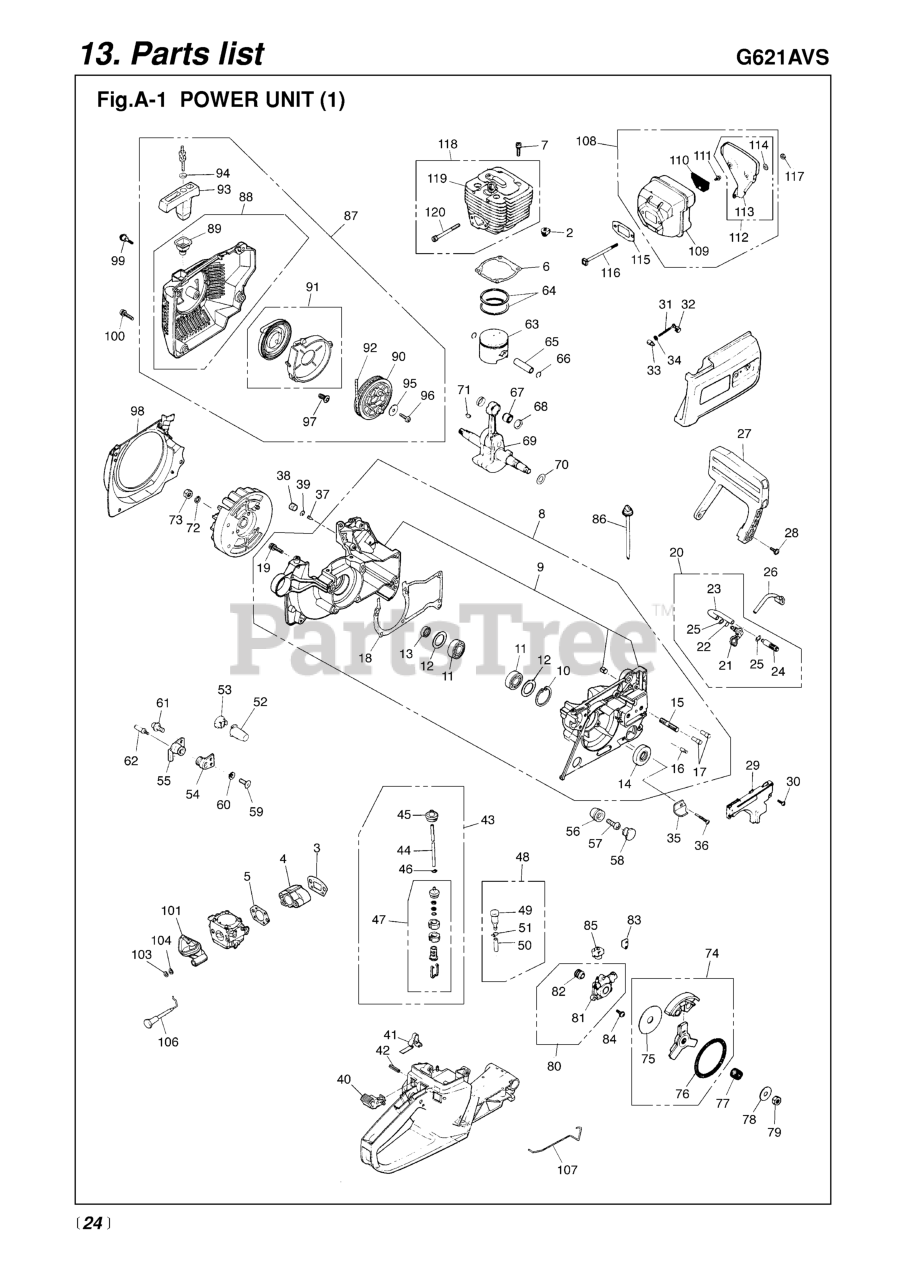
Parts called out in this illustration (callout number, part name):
2	GROMMET
3	GASKET, INS. (RPLS 2616-14112)
4	INSULATOR
5	GASKET, CARB (RPLS 2618-14131)
6	GASKET, CYLINDER (RPLS.-14210)
7	BOLT M5 x 20 (RPLS -12280)
8	CRANKCASE-ASSY
9	CRANKCASE (RPLS 2616-21101)
10	RING, SNAP, M35 X 1.5
11	BEARING (REPLACES 2810-21240)
12	RING
13	SEAL, OIL
14	SEAL (REPLACES 1400-21220)
15	STUD (RPLS 0205-50825)
16	PIN
17	PIN
18	GASKET (REPLACES 3356-21311)
19	BOLT M5 x 20 (RPLS -12280)
20	OIL PIPE COMP
21	PIPE, OIL
24	WEIGHT
26	PIPE, OIL
28	SCREW (REPLACES 2616-24320)
29	COVER, BRAKE (RPLS -24411)
30	SCREW, M5 x 14
31	ADJUST SCREW
32	STOPPER, ADJUS
33	NUT (A)
34	WASHER, M5 X .8
35	CATCHER, CHAIN (RPLS -25210)
37	VALVE (RPLS -23120)
38	SEAL, BREATHER
39	CLIP
40	SWITCH LEVER
41	SPRING
42	PIN, SPRING
43	PIPE ASSEMBLY
44	PIPE, SUCTION
45	GROMMET
46	CLIP (REPLACES 2841-31280)
47	FILTER ASSY
48	BREATHER ASSEMBLY
49	BREATHER ASSY (RPLS 2630-31270
51	CLIP (REPLACES 2841-31280)
52	DAMPER (RPLS -35111)
53	CAP (RPLS -35120)
54	DAMPER (RPLS -35150)
55	DAMPER (REPLACES -35131)
56	DAMPER (RPLS 2670-35110)
57	SCREW
58	CAP
59	SCREW, M5 X 14
61	SCREW
63	PISTON
64	RING
65	PIN, PISTON
66	RING, SNAP
67	BEARING
68	WASHER (RPLS 1491-41510)
69	CRANKSHAFT (RPLS -42003)
70	SHIM (REPLACES 848-870-G000)
71	KEY
72	WASHER, M10 X 25
73	NUT
74	CLUTCH ASSY (RPLS -51200)
75	PLATE
76	SPRING (RPLS -51230)
77	BEARING
78	WASHER
79	NUT
80	OIL PUMP (RPLS 3356-55102)
81	BODY, OIL PUMP
82	GEAR, WORM
83	GASKET, PUMP
84	SCREW, M5X20 (RPLS.1400-75510)
85	GROMMET (RPLS -55451)
86	SHAFT
87	STARTER ASSY (RPLS. -75003)
88	CASE (RPLS -75101)
89	GUIDE
90	REEL
91	SPRING COMP (RPLS. -75301)
92	ROPE
93	KNOB, STARTER
96	SCREW
98	COVER
99	SCREW (REPLACES 2616-75710)
100	SCREW
101	MANIFOLD (RPLS -82112)
103	WASHER, SPRING M4 x 1.3
104	WASHER, M5 X .8
106	ROD, CHOKE
107	ROD (RPLS 3356-82411)
109	MUFFLER (REPLACES 3359-15111)
110	ARRESTER, SPARK
111	SCREW, M4 X 8
112	MUFFLER GUARD SET
113	COVER (REPLACES 3357-15133)
114	WASHER
115	GASKET
116	BOLT
118	CYLINDER SET
119	CYLINDER (REPLACES 2618-12116)
120	BOLT (REPLACES 3356-82211)
